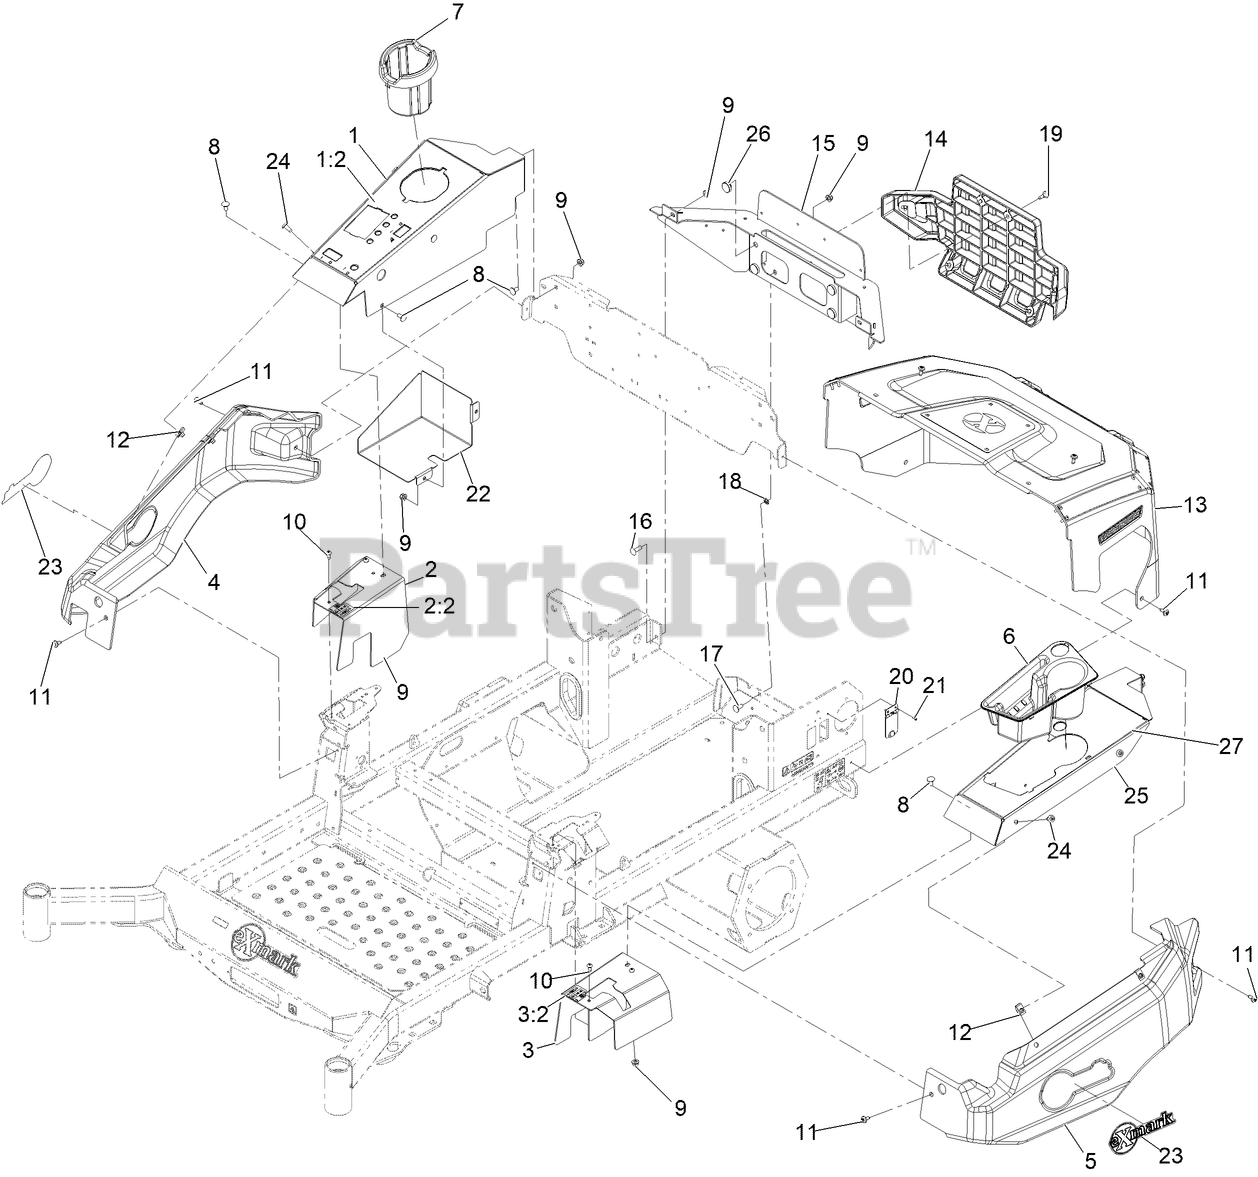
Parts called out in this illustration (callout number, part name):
1	ASM-RH Control Panel
1:2	DECAL-CONTROL PANEL
2	ASM-RH Cover
2:2	DECAL-CONTROL LEVER, RH
3	ASM-LH Cover
3:2	DECAL-CONTROL LEVER, LH
4	Sidepod-RH
5	Sidepod-LH
6	CUPHOLDER, LT
7	CUPHOLDER, RT
8	SCREW-CARR
9	NUT-HF, NI
10	SCREW-TPH THD FORM
11	SCREW-SHOULDER
12	NUT-CLIP, U
13	ASM-Hood
14	BUMPER-REAR
15	Guard-Rear [red]
16	SCREW-CARR
17	SCREW-CARR
18	NUT-PUSH
19	SCREW-SHOULDER
20	PLATE-COVER, SPRING
21	RIVET
22	PLATE-ELECTRICAL COVER
23	DECAL, EXMARK LOGO
25	Console-LH Support
26	BUMPER-SEAT
27	DECAL-LH SIDE POD
